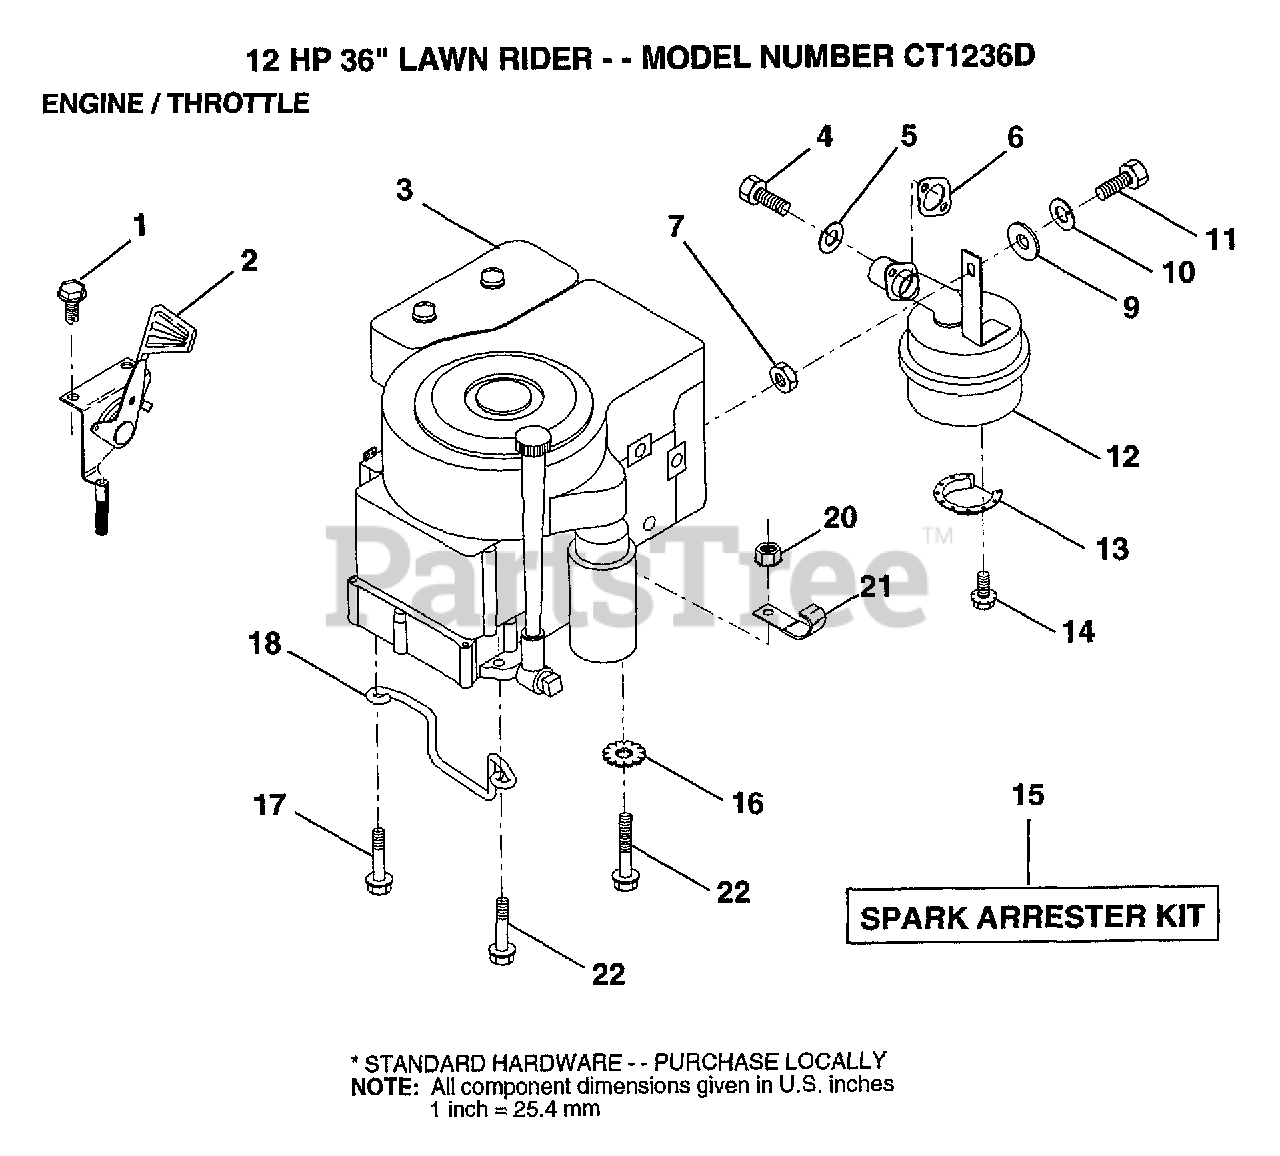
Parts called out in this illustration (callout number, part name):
1	SCREW
2	THROTTLE CONTROL
4	SCREW
5	LOCKWASHER
7	NUT.HEX.5/16-18
10	LOCKWASHER
12	MUFFLER
13	DEFLECTOR.222573
16	LOCKWASHER
17	SCREW LT
18	"KEEPER,DR BELT GR"
20	NUT
21	CLIP T
22	SCREW LT
